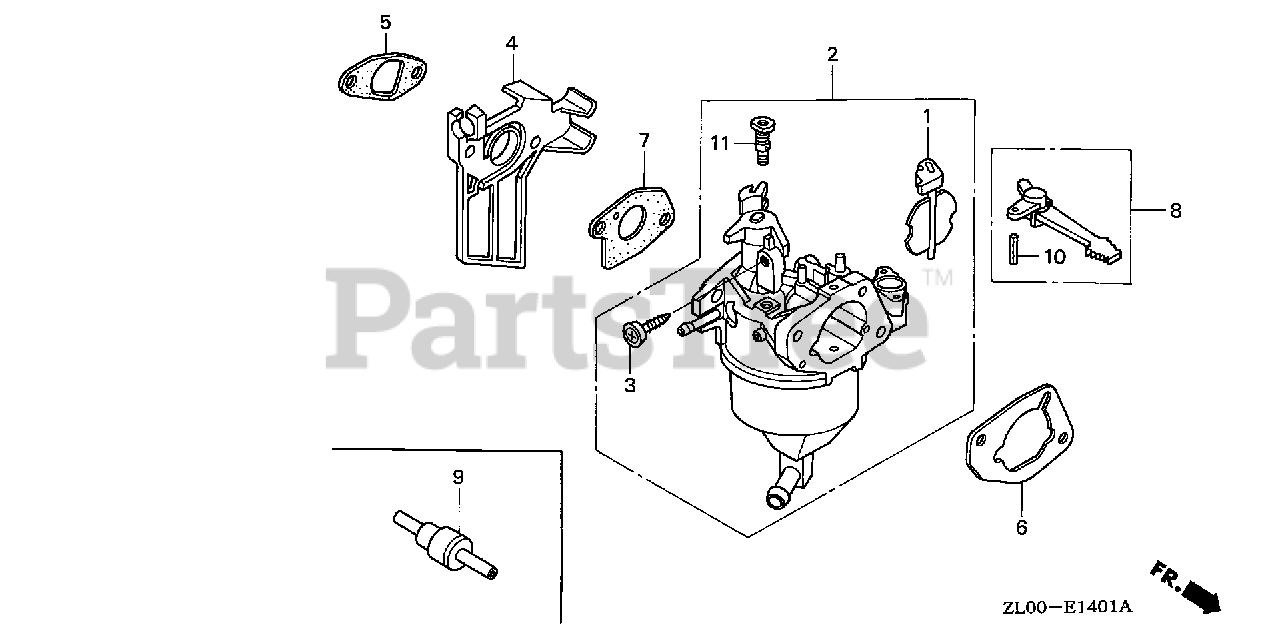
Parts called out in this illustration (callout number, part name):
2	CARBURETOR ASSY. (BEL1A A)
3	SCREW, THROTTLE STOP
4	INSULATOR, CARBURETOR
5	GASKET, INSULATOR
6	SPACER, CARBURETOR
7	GASKET, CARBURETOR
8	LEVER, CHOKE (STD)
9	VALVE, DASHPOT CHECK
10	PIN, SPRING (2X12)
11	JET, PILOT (#35)
